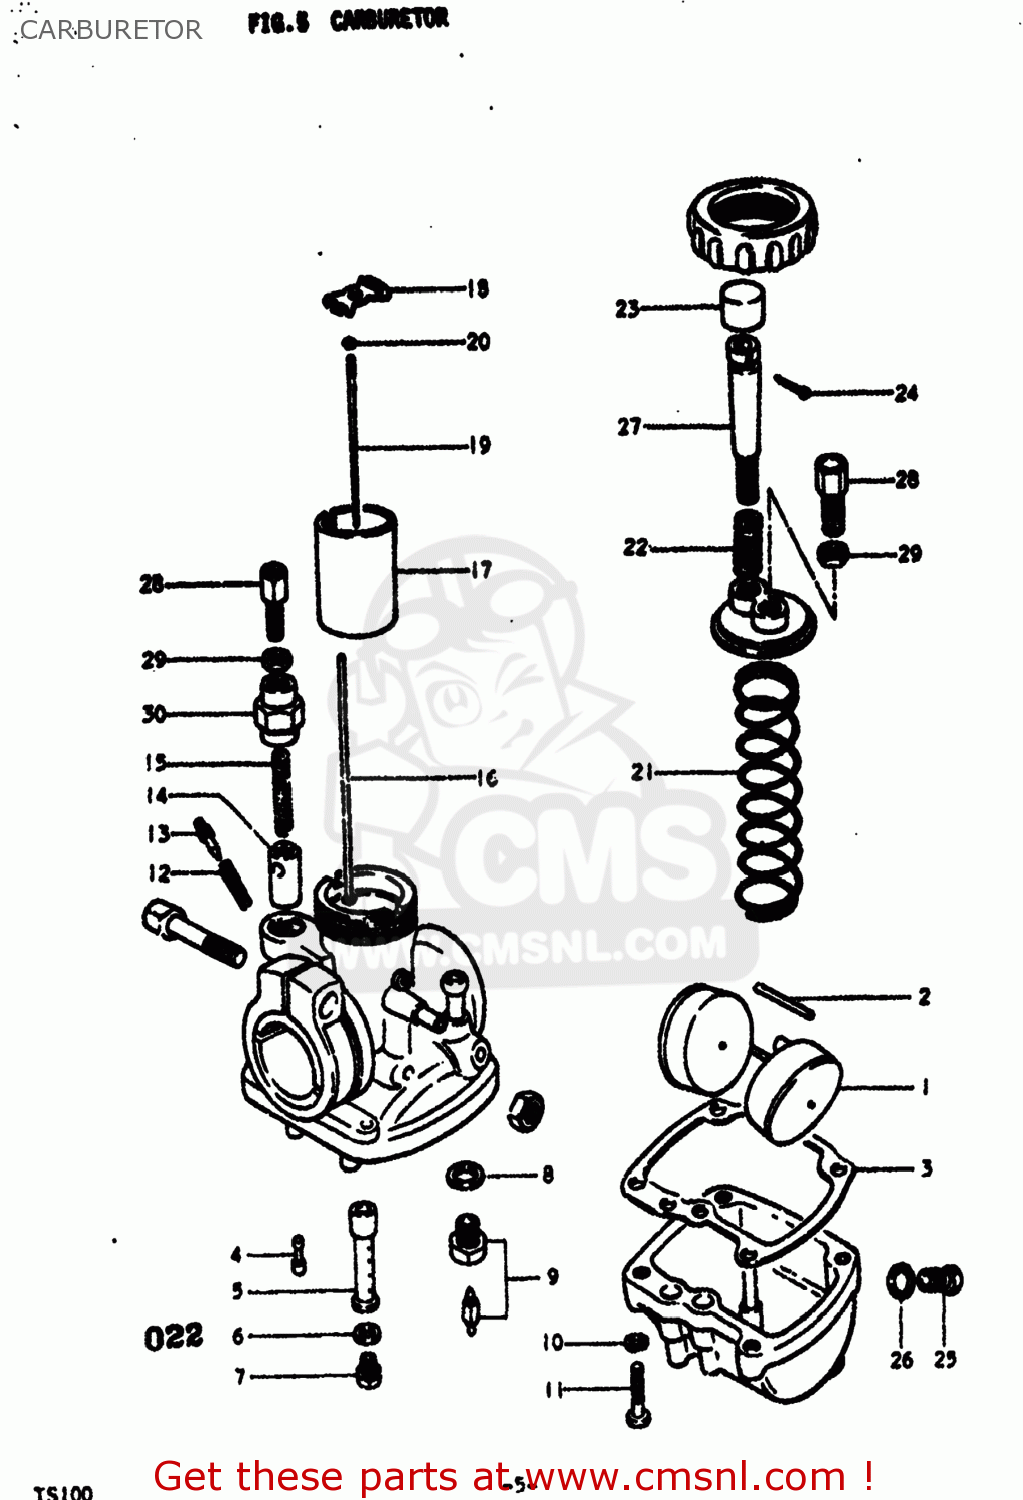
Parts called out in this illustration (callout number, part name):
0	CARBURETOR ASSEMBLY
1	FLOAT
2	PIN,FLOAT
3	GASKET,FLOAT CHAMBER (NAS)
4	JET
5	JET,NEEDLE
6	WASHER
7	JET,MAIN
8	GASKET,NEEDLE VALVE (NAS)
9	VALVE ASSY,NEEDLE
10	LOCK WASHER
11	SCREW
12	SPRING
13	SCREW,PILOT AIR
14	PLUNGER,STARTER
15	SPRING
16	ROD,THROTTLE VALVE ADJUST
17	VALVE,THROTTLE
18	STOPPER,NEEDLE CLIP
19	NEEDLE.JET
20	CLIP,NEEDLE
21	SPRING,THROTTLE VALVE
22	SPRING,THROTTLE STOP SCREW
23	CAP,THROTTLE VALVE STOP SCREW
24	PIN 12X10
25	PLUG
26	GASKET,DRAIN,PLUG (NAS)
27	SCREW,THROTTLE STOP
28	ADJUSTER,CABLE
29	NUT
30	CAP,STARTER PLUNGER
